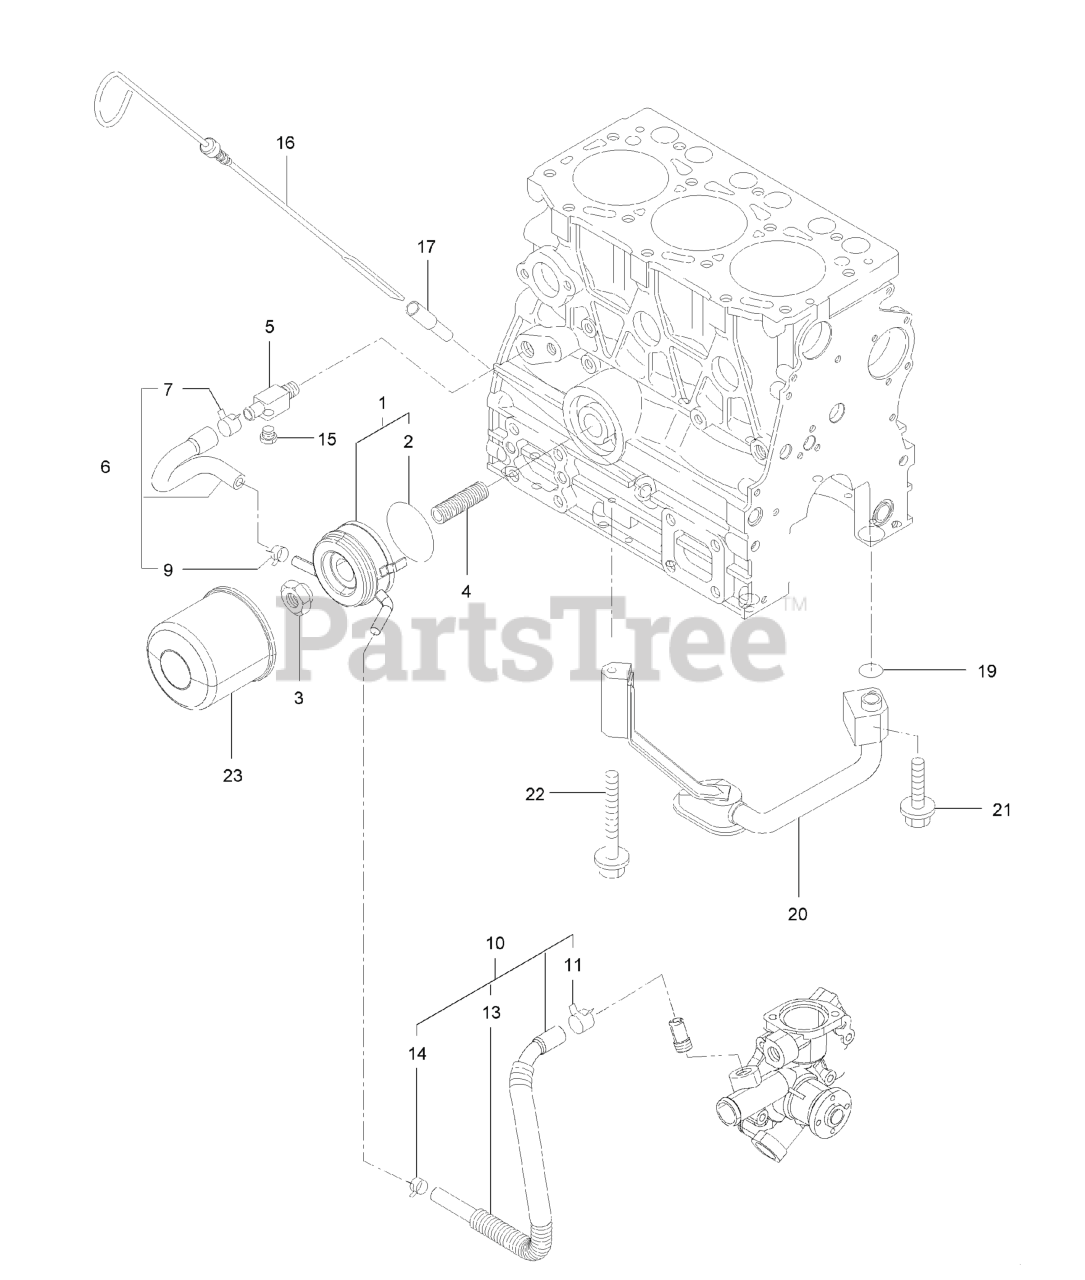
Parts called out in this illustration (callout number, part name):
1	COOLER-OIL
3	NUT-COOLER, OIL
4	STUD-LO FILTER
6	PIPE ASM-COOLER IN
9	CLAMP-HOSE
10	PIPE ASM
14	CLAMP-HOSE
15	PLUG-DRAIN
16	DIPSTICK
17	GUIDE-DIPSTICK
20	PIPE ASM-OIL INLET
23	FILTER ENGINE OIL
